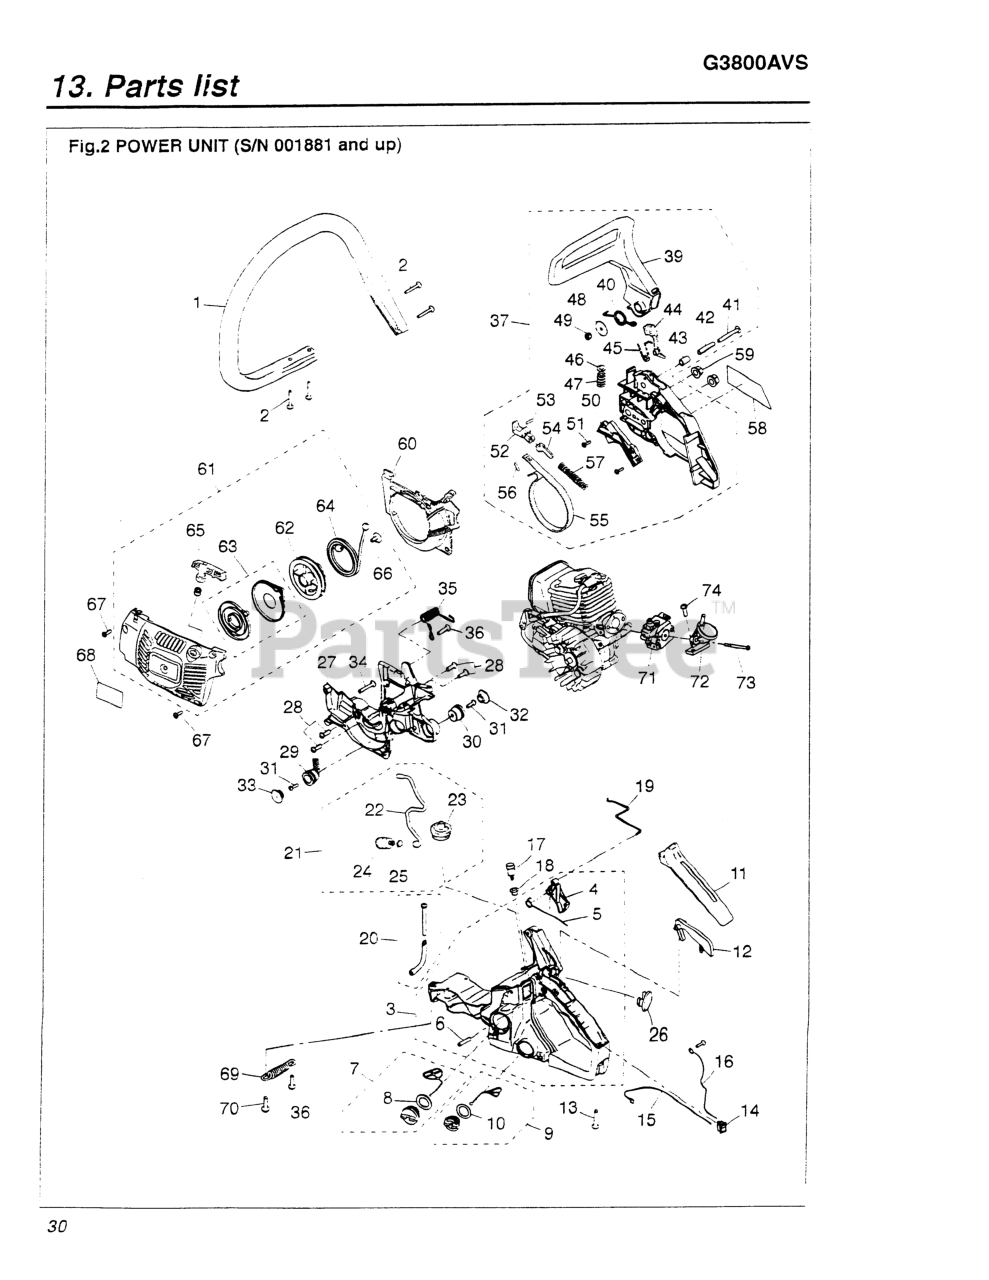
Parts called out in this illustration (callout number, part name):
1	HANDLE, LEFT
3	HANDLE, RIGHT ASSEMBLY
4	LEVER, THROTTLE
5	SPRING
7	CAP ASSEMBLY
8	GASKET
9	CAP ASSEMBLY
10	GASKET
11	COVER, GRIP
14	SWITCH ASSEMBLY
15	CORD, SWITCH
17	BREATHER ASSEMBLY
18	GROMMET
19	ROD, THROTTLE
20	PIPE COMPLETE
21	PIPE ASSEMBLY
22	PIPE, FUEL
24	5500-85400 (RRLS. 1750-85300)
25	CLIP (REPLACES 2841-31280)
26	CAP
27	CASE, ENGINE
28	SCREW (REPLACES 2616-24320)
29	DAMPER COMPLETE
30	DAMPER (RPLS 2670-35110)
32	CAP
33	CAP
35	SPRING, REAR
36	SCREW (USE 848-825-1901)
37	CHAIN BRAKE ASSY (RPLS 2850- )
39	GUARD, FRONT
40	SPRING, RETURN
43	SPACER (RPLS -54210)
46	PLATE, STOPPER
48	WASHER (RPLS -75410)
49	NUT (B)
50	COVER, SPRING
51	SCREW
52	LEVER, BRAKE COMPLETE
54	ARM, SLIDE
55	BAND, BRAKE
56	PIN
57	SPRING, BRAKE (RPLS. 50030121)
58	LABEL (RPLS-53120)
59	NUT
60	COVER, FAN
61	STARTER ASSEMBLY
62	REEL
63	SPRING
65	KNOB (RPLS -75420)
66	SCREW (RPLS -75150)
68	LABEL (G3800AVS)
69	SPRING, FRONT
70	SCREW (REPLACES 2616-24320)
71	CARBURETOR ASSEMBLY
72	MANIFOLD
73	BOLT
